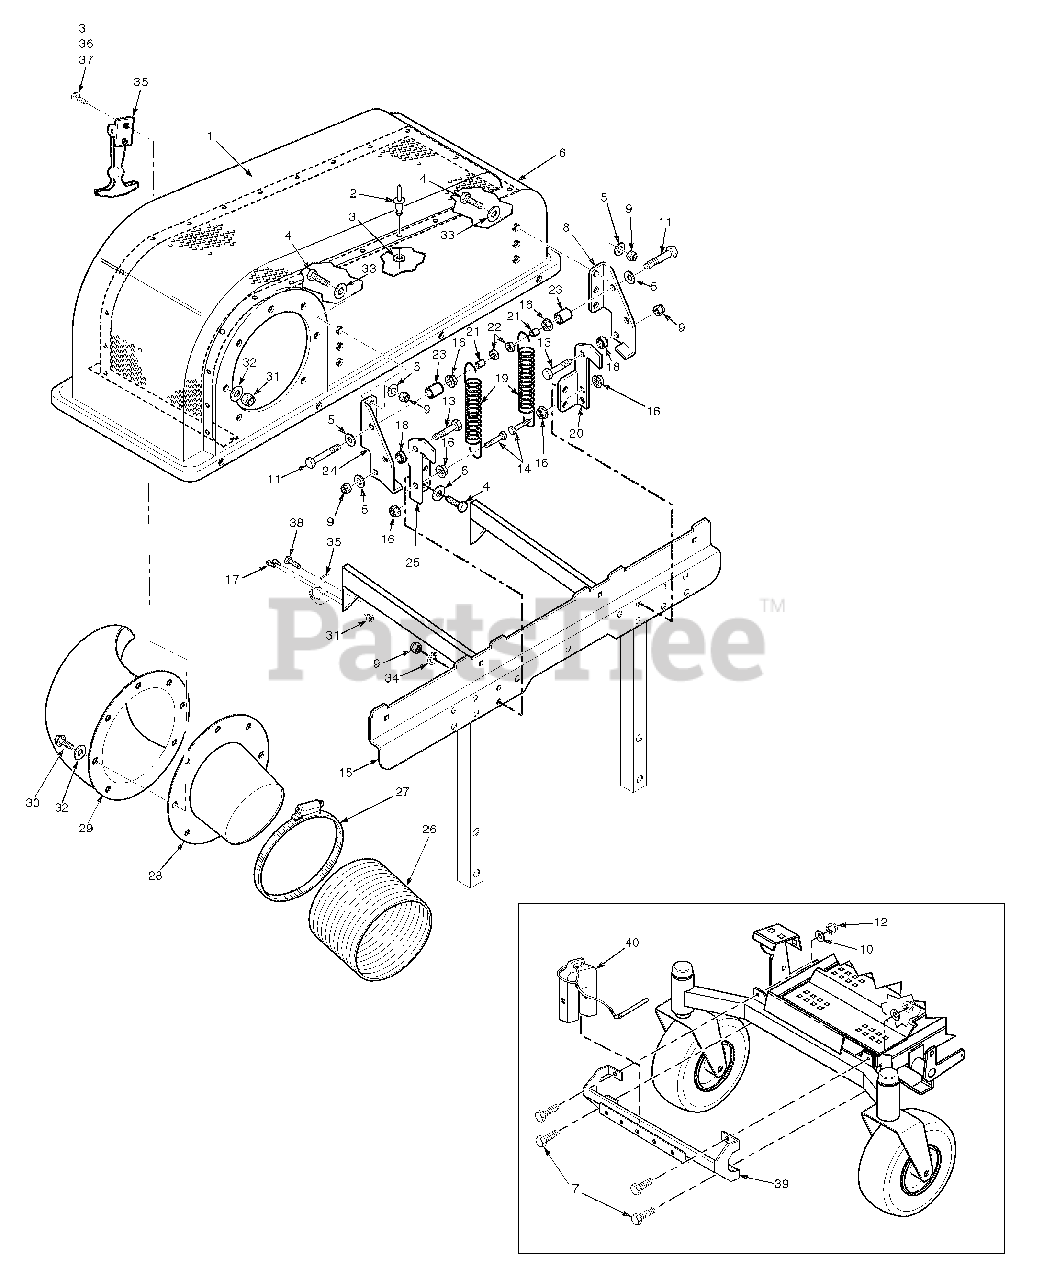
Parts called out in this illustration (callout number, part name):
1	Screen, Catcher Hood
2	Pop Rivet, 3/16 x .652
3	Flatwasher, 3/16-.196 x .469 x .048
4	Bolt, Hex Head 3/8-16 x 1-1/4"
5	Flatwasher, 3/8-.391 x .938 x .105
6	Hood Assembly, GC-STT
7	Bolt, Hex Head 7/16-14 x 1-3/4"
8	Hinge, Upper LH
9	Nut, Elastic Stop 3/8-16
10	Flatwasher, 7/16-.500 x 1-1/4"
11	Bolt, Hex Head 3/8-16 x 2-1/4"
12	Nut, Elastic Stop 7/16-14
13	Bolt, Hex Head 3/8-16 x 1-1/2"
14	Bolt, Hex Head 3/8-16 x 1-3/4" Grade 8
15	Support Weldment, Bag Frame
16	Nut, Serrated Flange 3/8-16
17	Rivet, 3/16 x .402 POP
18	Bushing, Hopper Pivot
19	Spring, Hood Hinge
20	Hinge, Lower LH
21	Spacer
22	Locknut, 3/8-16
23	Spacer
24	Hinge, Upper RH
25	Hinge, Lower RH
26	Hose, 8" Dia. x 60-1/2"
27	Clamp, 8-5/8" Max Dia.
28	Tube, Filler
29	Elbow
30	Bolt, Hex Head 5/16-18 x 1-1/4"
31	Nut, Elastic Stop 5/16-18
32	Flatwasher, 5/16-.375 x .875 x .083
33	Flatwasher, 3/8- .406 x 1-1/2" x .179
34	Lockwasher, 3/8" Spring
35	Latch
36	Screw, #10-32 x 3/4"
37	Nut, Elastic Stop #10-32
38	Bolt, Hex Head 5/16-18 x 3/4"
39	Support Weldment, Weights
40	Weight Assembly
